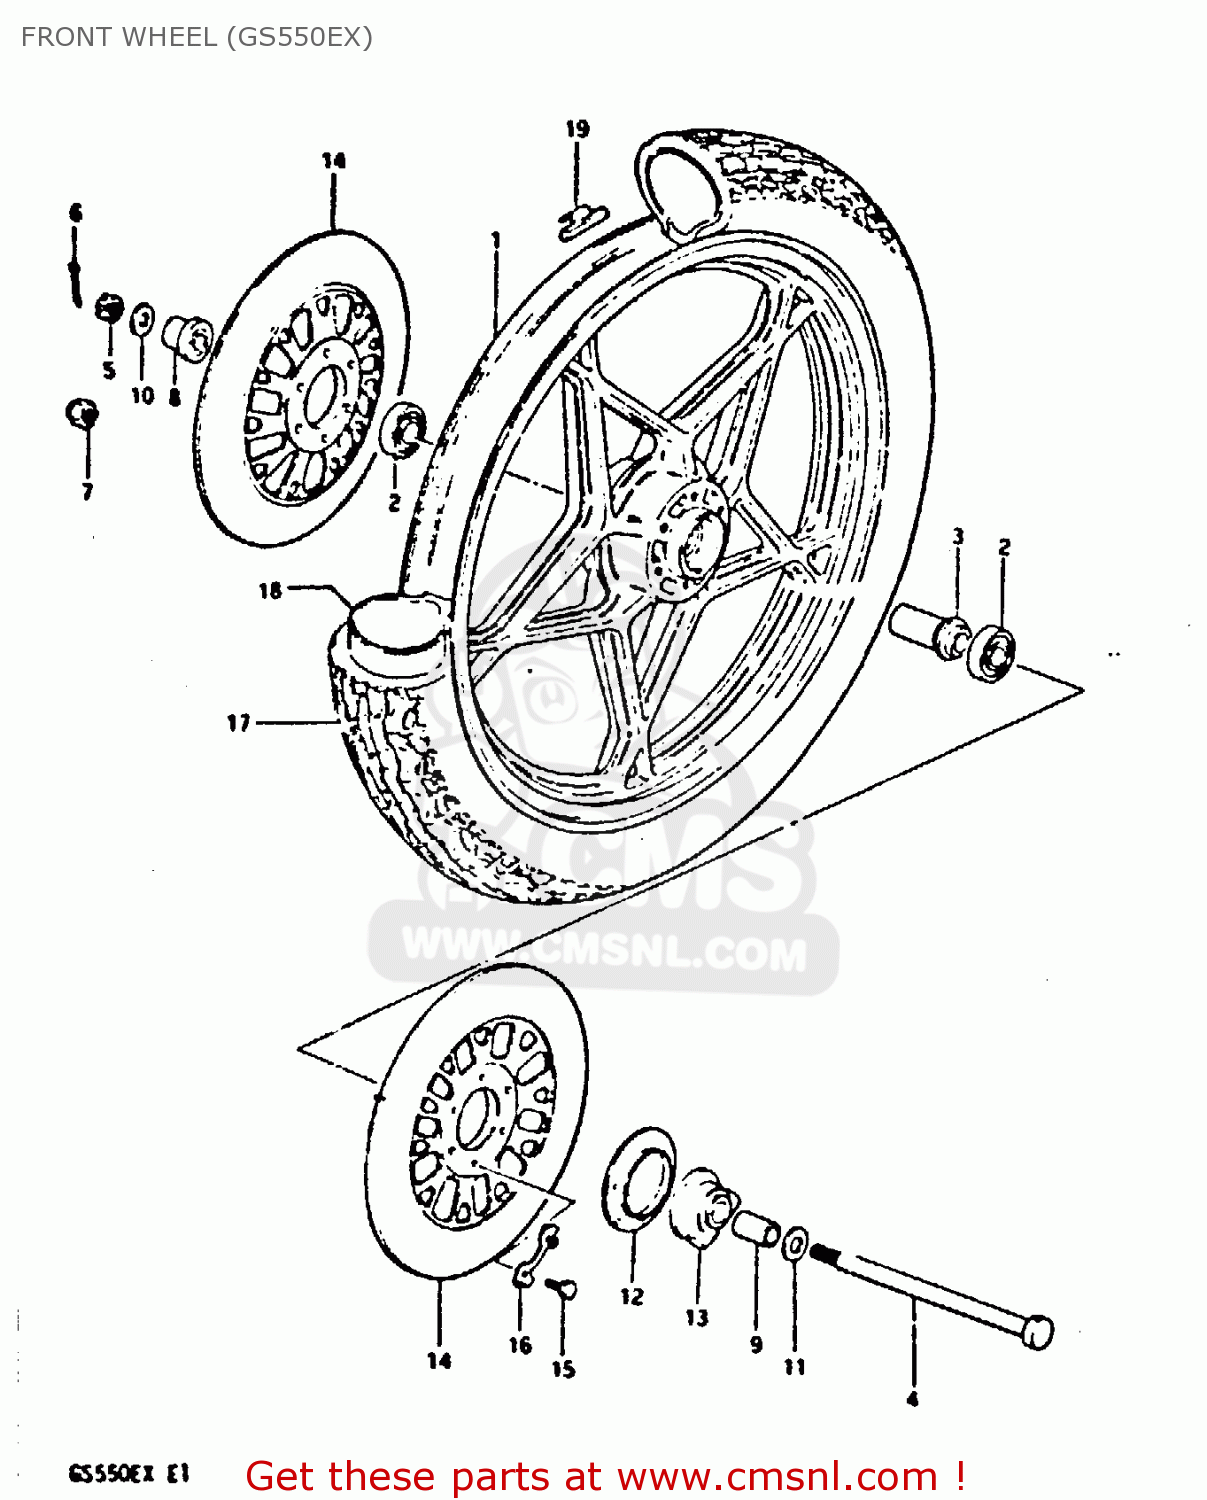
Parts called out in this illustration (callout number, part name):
1	WHEEL, FRONT
2	BEARING
3	SPACER,FR HUB BEARING
4	AXLE,FRONT
5	NUT 12MM
6	COTTER PIN
8	SPACER,FR HUB BEARING,R
9	SPACER(15X22X30)
10	WASHER
12	DUST SEAL,SPEEDOMETER GEAR BOX
13	BOX ASSEMBLY,SPEEDOMETER GEAR
14	DISK, FRONT BRAKE
15	BOLT(8X25)
16	WASHER
17	TIRE,FRONT
18	TUBE,INNER
19	BALANCER,WHEEL
